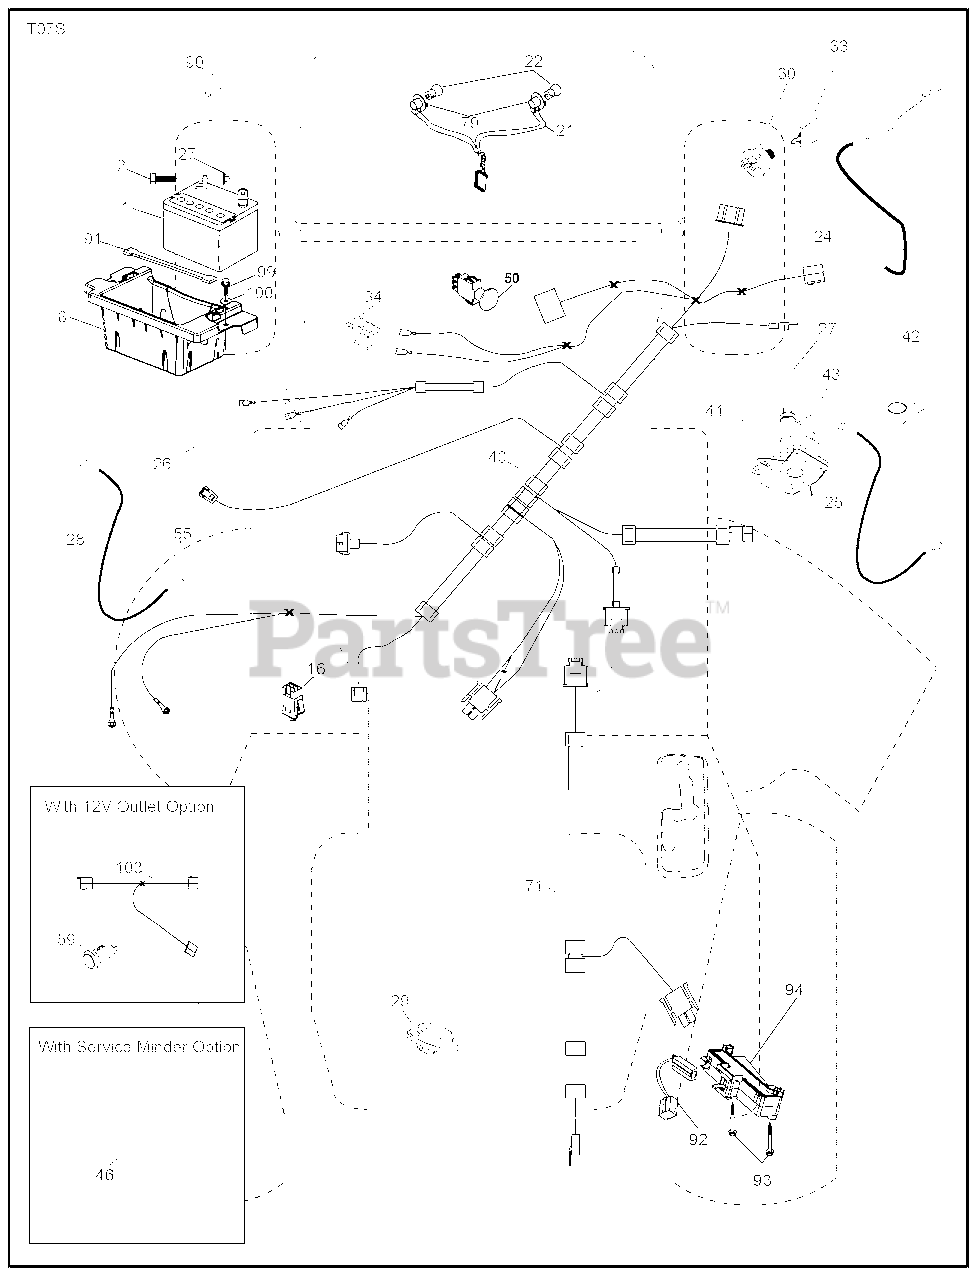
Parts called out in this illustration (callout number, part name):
1	Battery
2	Bolt Hex Hd 1/4-20 unc x 3/4
8	Battery Box
16	Switch Interlock
21	Harness Socket Light
22	Bulb, Light # 1156
24	Cable Battery
25	Cable Starter
27	Nut Keps Hex 1/4-20 unc
28	Cable Ground 21" Blk 6 Ga.
29	Switch Seat
30	Switch Ign
34	Switch Light/Reset
40	Harness Ign. Dash
41	Screw Thd Cut 1/4-20 x 1/2
42	Cover Terminal Red
43	Solenoid
46	Gauge Hourmeter
50	Switch PTO
55	Screw Thdrol 5/16-18 x 3/4
59	Outlet 12-Volt
71	Harness Ign
79	Socket Asm Bulb Twistlock
90	Cover Terminal Battery
91	Strap Battery
92	Harness Pigtail Console ROS
93	Screw Plastite 10-14 x 2.0
94	Module Reverse ROS
99	Screw Hexwsh Thdrol 1/4-20 x 3/4
100	Washer 9/32 x 7/8 x 16 Ga.
103	Harness Pigtail 12V Outlet
